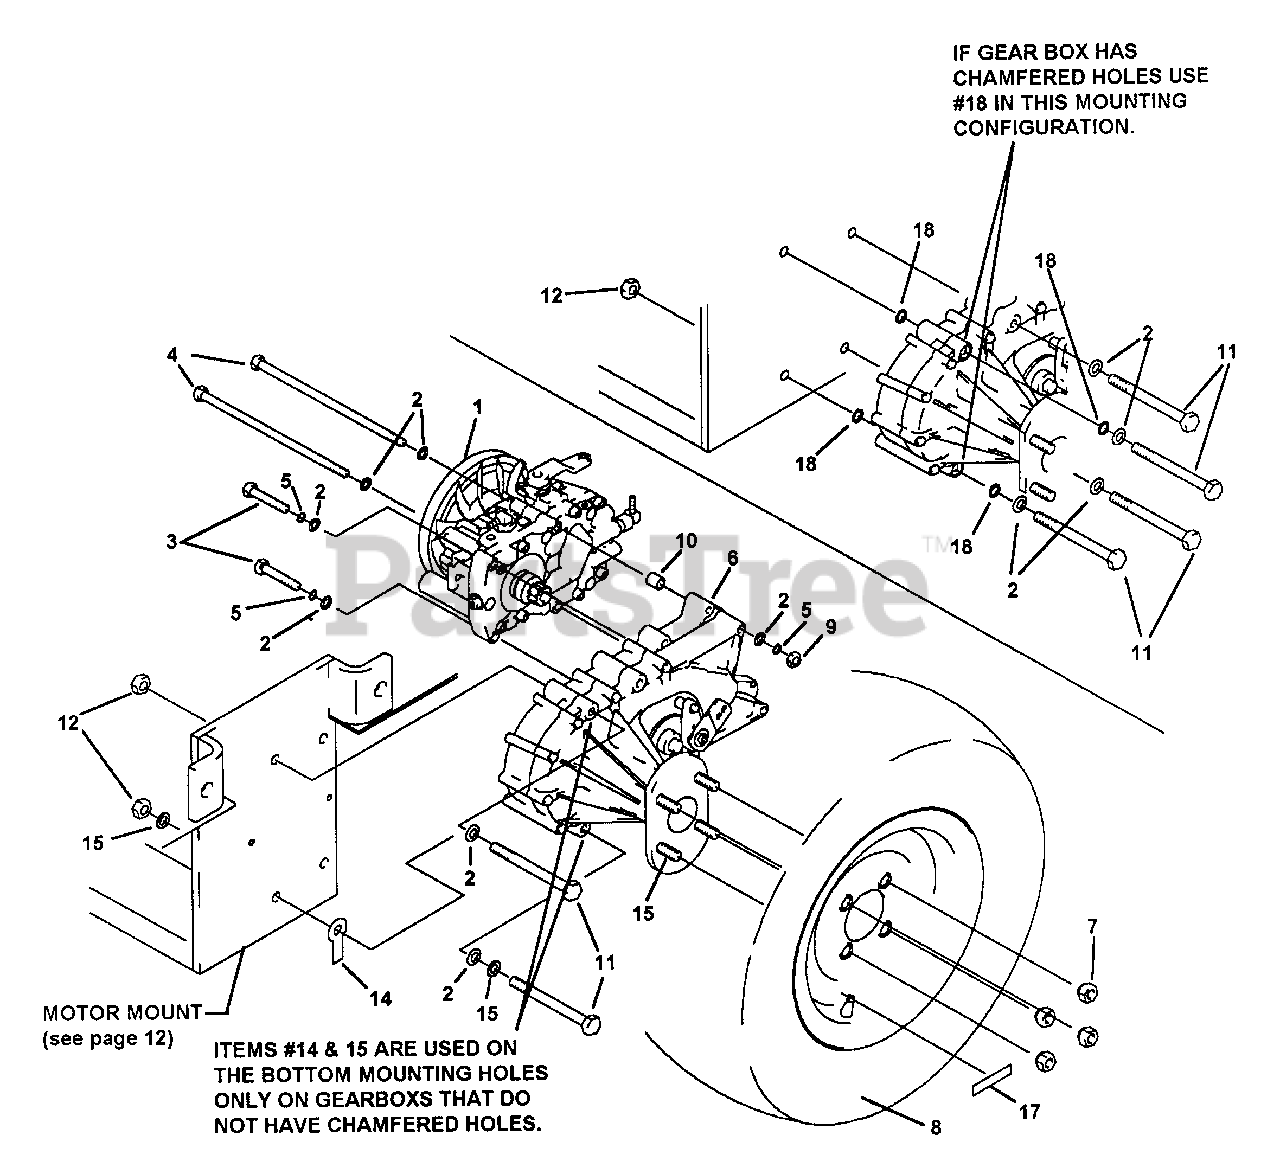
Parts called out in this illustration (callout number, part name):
1	HYDROSTAT TRANSMISSION ASSEMBLY L.H.
2	WASHER, FLAT STD. 5/16"
3	BOLT, 5/16-18 X 1-3/4" GR. 5
4	BOLT, 5/16-18 X 7-1/2" GR. 5
5	LOCKWASHER, 5/16" SPLIT SPRING
6	GEAR BOX, L.H.
7	NUT, LUG 60 DEGREE, 1/2-20
8	TIRE, 20-10.00-10, 4 PLY W/RIM, DICO BRAND
9	NUT, 5/16-18 PLAIN
10	BUSHING
11	BOLT, 3/8-16 X 4" GR.5
12	NUT, 3/8-16 NYLOC
14	HYDROGEAR BDV-10 GASKET CUT OUT
15	BOLT SEALING WASHER
17	DECAL, "TIRE PRESSURE..."
18	O-RING,GEARBOX
